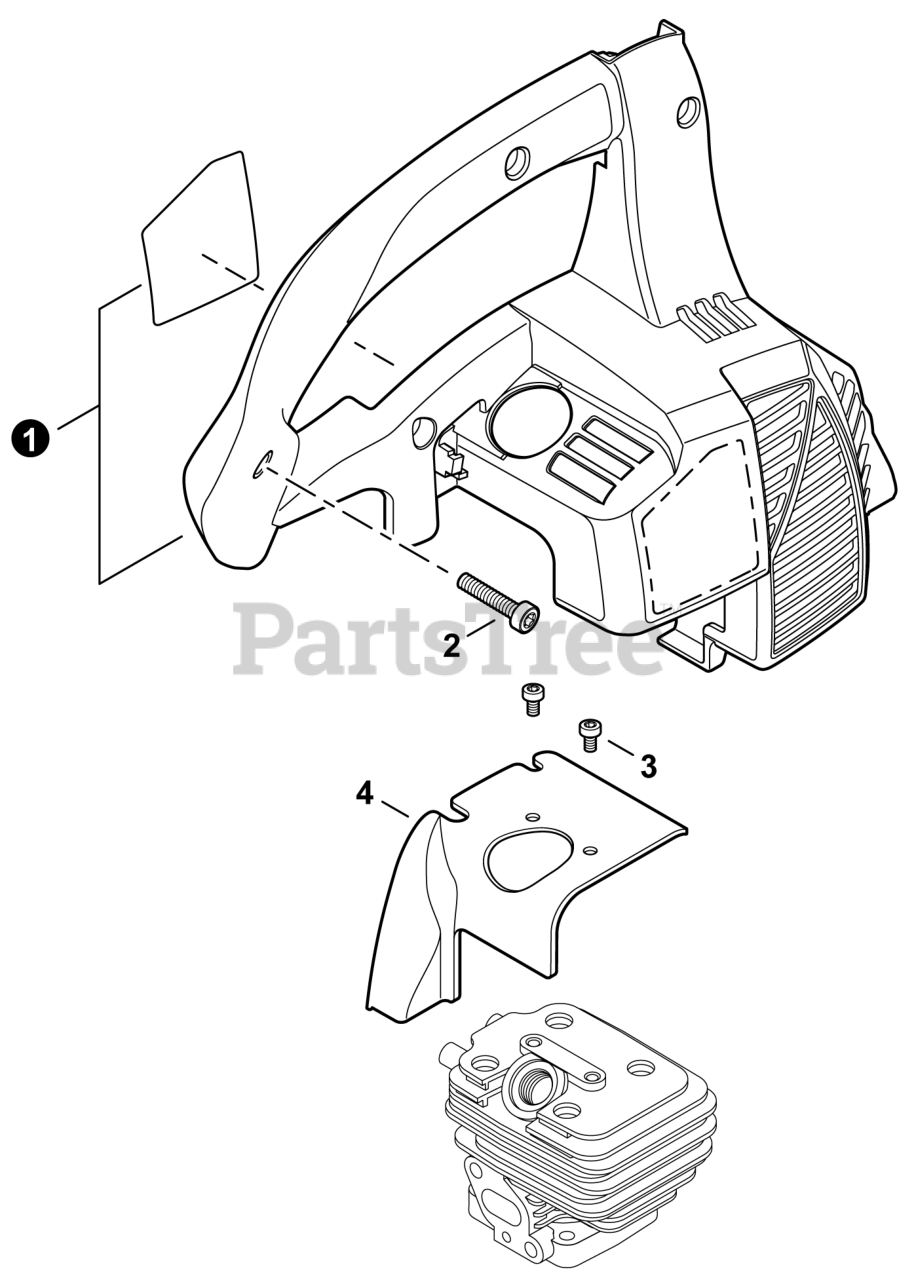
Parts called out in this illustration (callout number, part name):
1	COVER SET, ENGINE
2	BOLT, TORX 5x20
3	BOLT, TORX 5x8
4	SHIELD, CYLINDER
